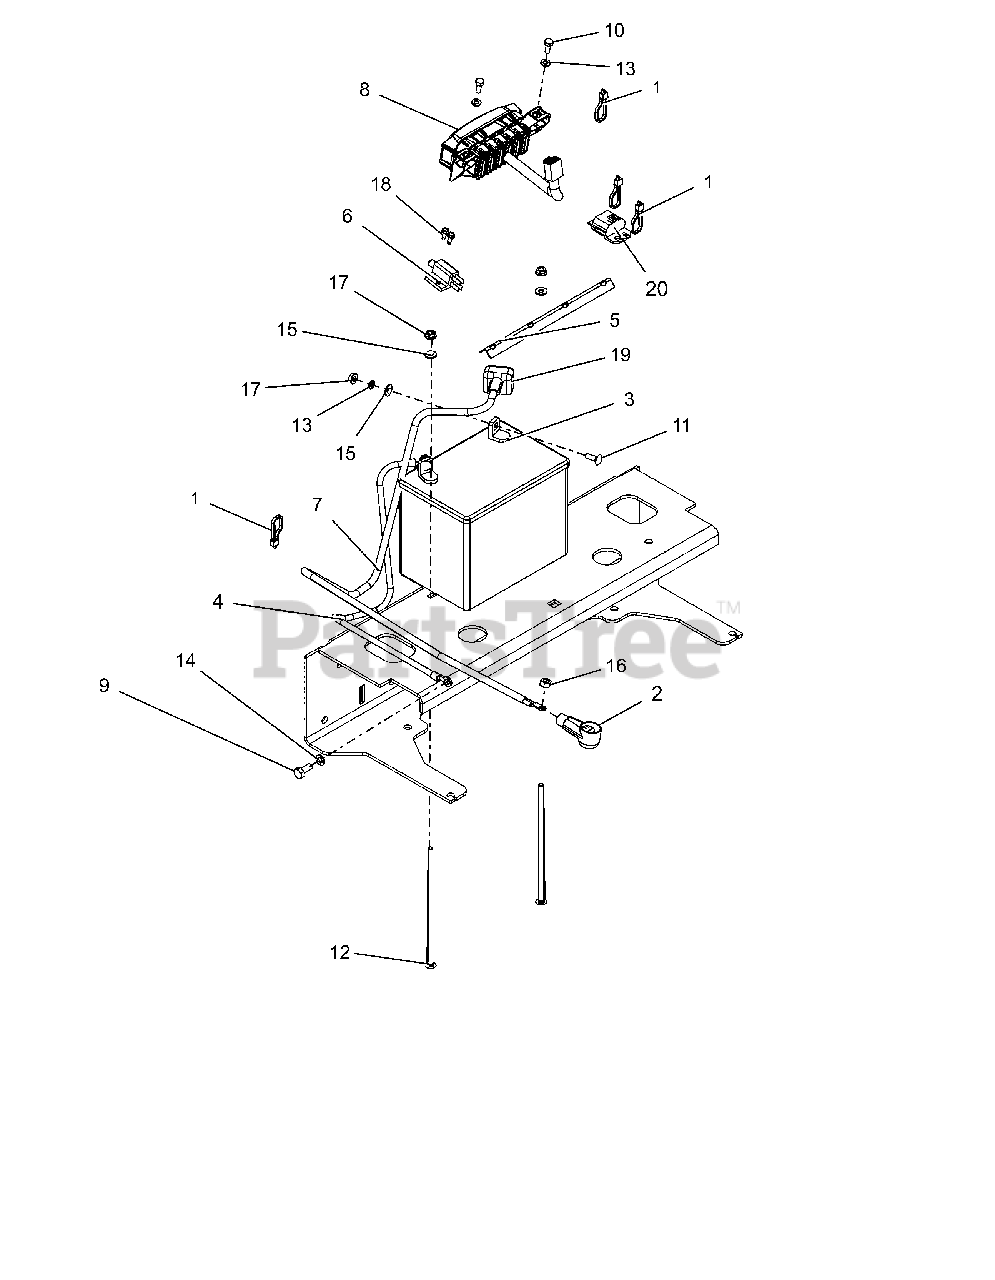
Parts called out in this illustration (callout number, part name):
1	CABLE TIE, .15 X 8.50
2	BOOT, BATTERY TERMINAL-RED
3	BATTERY, 300 CCA 10U1L
4	CABLE-NEGATIVE BATTERY 35.00"
5	HOLD DOWN
6	SWITCH- DOUBLE POLE N.O./N.O.
7	CABLE, BATTERY - 42" POSITIVE
8	HARNESS, PROSTANCE WIRING
8	FUSE,10 AMP MINI-ATC
8	FUSE,15 AMP MINI-ATC
8	FUSE,20 AMP MINI ATC
8	RELAY,MICRO5 TERML W/RESISTOR
8	DIODE, CONNECTOR SHELL
8	FUSE, 20 AMP BLADE S/O
9	@BLT-HEX M8-1.25X20 YWZC
10	@BLT-HEX M6-1X16 YWZC
11	@BLT-RDHDSQNK .25-20X.75 G5YZ
12	BLT-RDHDSQNK .25-20X7.50 GR2YZ
13	@WSHR-LK .25X.062 REG YWZC
14	@WSHR-LK .31X.078 REG YWZC
15	@WSHR-FL-STL.281X.62X.065 YWZC
16	NUT-LK-TOP M8-1.25 YWZC
17	@NUT-SPNLK-FLG .25-20 YWZC
18	@SCR-TAP 10-24X.50 HWH TR YWZC
19	INSULATOR
20	MODULE,INTERLOCK,DELAY, 1801
